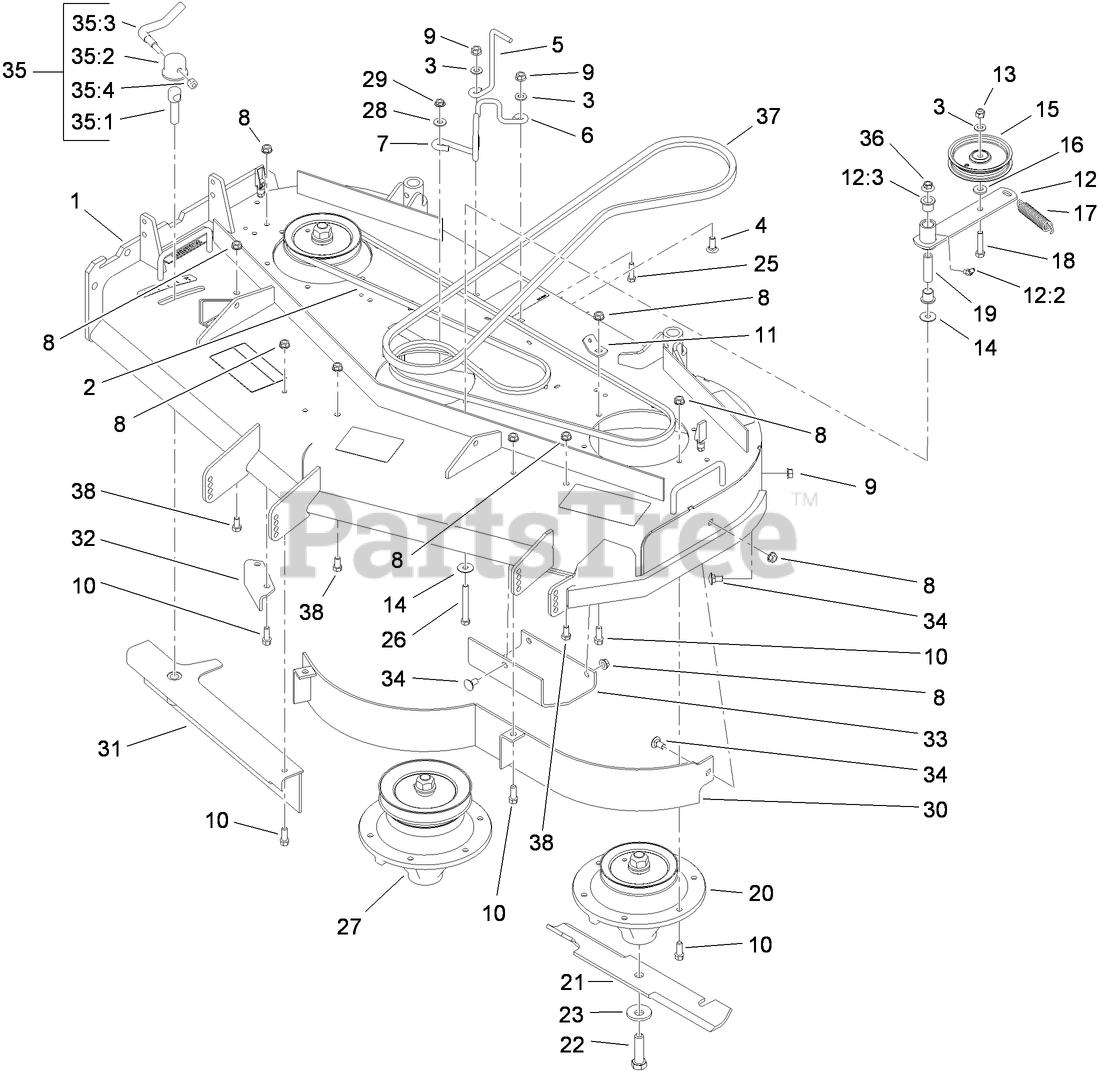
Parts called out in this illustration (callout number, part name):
1	DECK ASM
2	BELT-V
3	WASHER-FLAT
4	SCREW-CARR
5	GUIDE-BELT
6	GUIDE-BELT
7	GUIDE-BELT
8	NUT-HHF, WHIZ
9	NUT-HF
10	SCREW-HWH
11	PLATE-SPRING
12	IDLER ARM ASM
12:2	FITTING-LUBE, 45 DEG
12:3	BUSHING-FLANGE
13	NUT-LOCK, NI
14	WASHER
15	PULLEY-IDLER
16	WASHER-SPACER
17	SPRING-EXTENSION
18	SCREW-HH
19	SPACER
20	SPINDLE ASM
21	BLADE-16.5 INCH (HIGH FLOW)
22	SCREW-BLADE
23	Washer-Blade Bolt, Heavy
25	SCREW-HH
26	SCREW-HH
27	SPINDLE ASM
28	WASHER-FLAT
29	NUT-HF
31	ADJUSTABLE BAFFLE ASM
32	BAFFLE-DISCHARGE
34	SCREW-CARR
35	LEVER ASM
35:1	Screw-Lock
35:2	CAP-LOCK
35:3	Lever-Lock
35:4	NUT-LOCK, NI
36	NUT-HF
37	BELT-V
38	SCREW-HH
